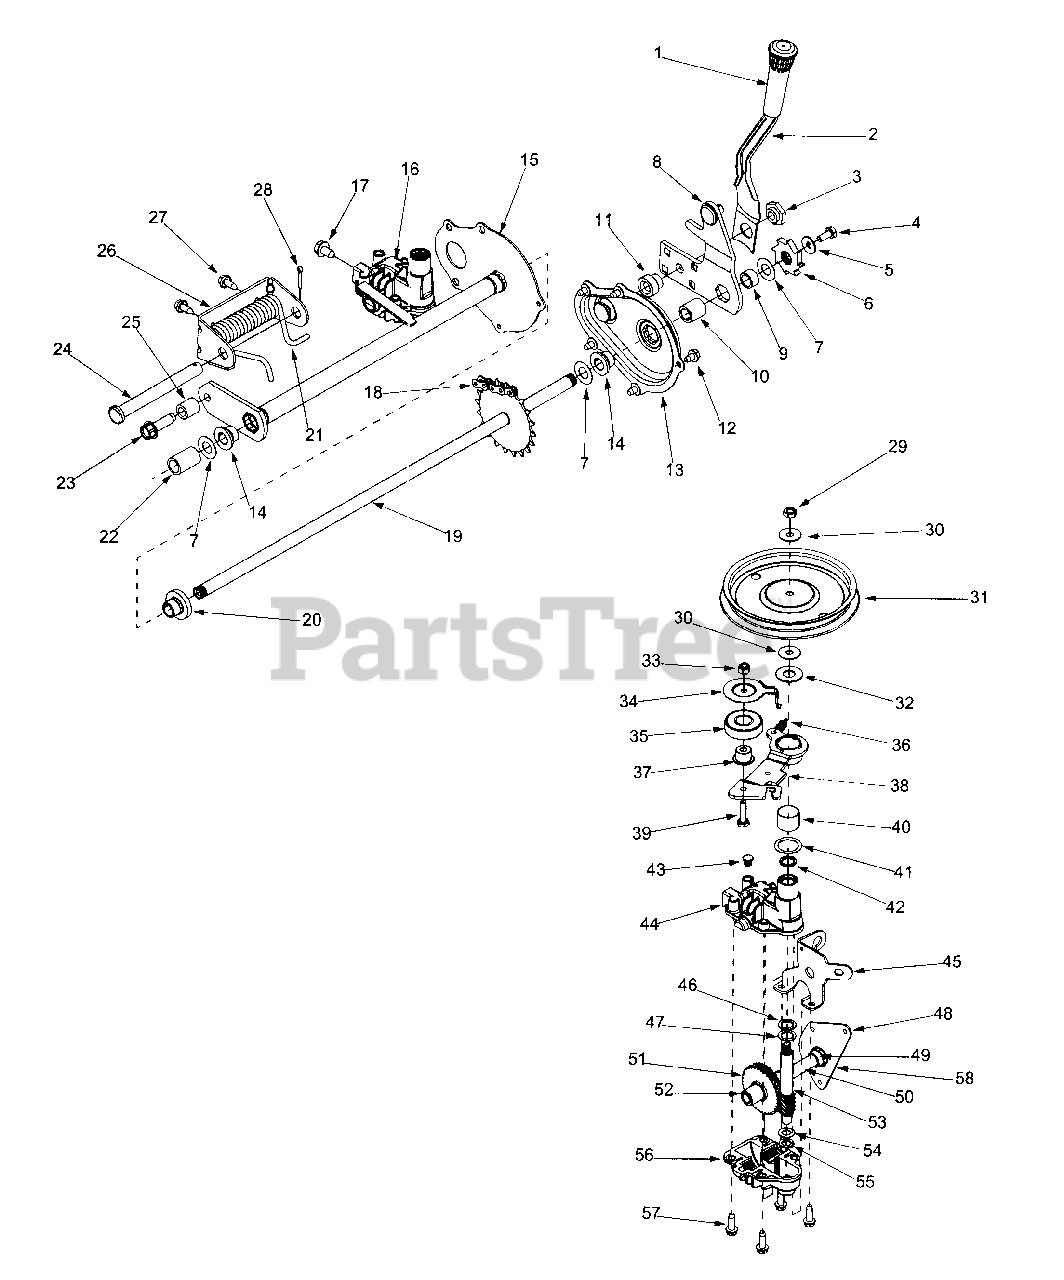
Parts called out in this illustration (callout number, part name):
3	Shoulder Nut .825 x .165 Lg.
4	Cap Screw 1/4-20 x .620
5	Bell Washer .285 ID x .75 OD
6	Wheel Rachet
7	Flat Washer .508 ID x 1.0 OD
9	Spacer .510 ID x .70 OD
10	Sleeve Bearing .504 ID x .830 OD
11	Shoulder
12	Tap Screw 1/4-20 x .375
16	Transmission Assembly
17	Hex Screw 5/16-18
18	Chain
19	Rear Axle Assembly
20	Flange Bearing .506 ID x .715 Lg
21	Torsion Spring
22	Spacer .550 ID x .750 OD
23	Screw 3/8-16 x .25
24	Clevis Pin .50 Dia x 4.82 Lg.
25	Spacer .385 ID x .624 OD
29	Hex Jam Nut 5/16-24
30	Bell Washer .325 ID x .930 OD
32	Flat Washer .510 ID x 1.120 OD
33	Hex Jam Nut 1/4-28
35	Bearing
36	Extension Spring
37	Flange Spacer
38	Idler Bracket Assembly
39	Hex Cap Screw 1/4-28 x 1.0
40	Bearing Sleeve
41	Flat Washer .885 ID x 1.45 OD
42	Oil Seal
44	Upper Housing Assembly
47	Thrust Washer .504 ID x .70 OD
48	Pivot Bracket
49	Flange Bearing
50	Output Shaft 6T
52	Bearing
53	Pinion Shaft 10T
54	Thrust Washer 3/8 x .70
55	Thrust Washer .388 x .625
56	Lower Housing Assembly
57	Hex Screw 1/2-20 x .75
58	Shaft Assembly
